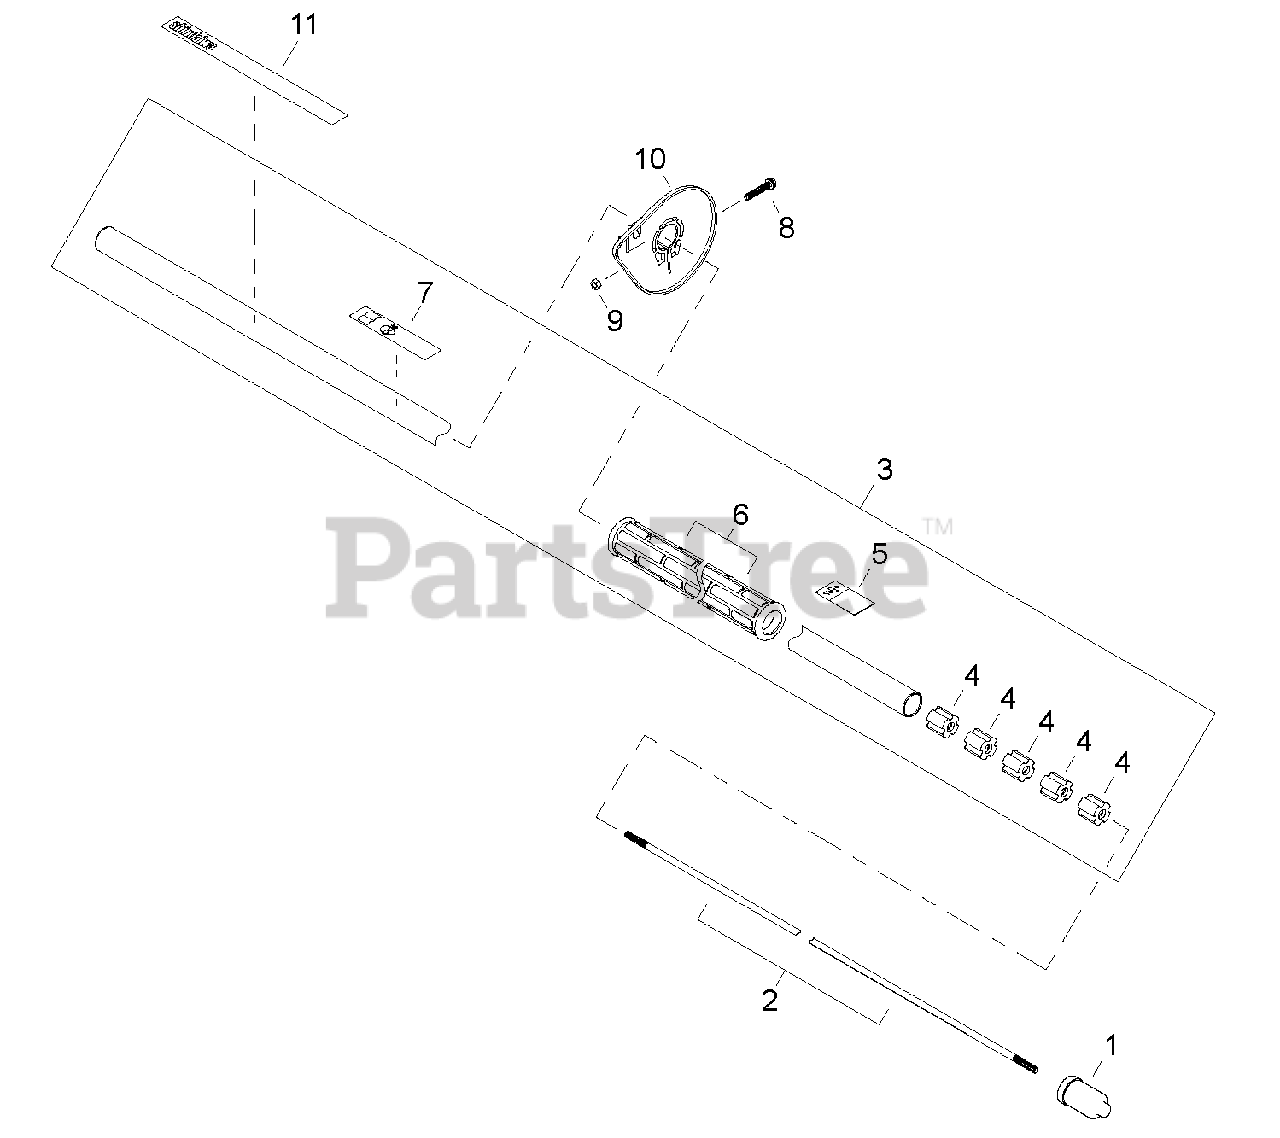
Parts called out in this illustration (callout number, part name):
1	CAP
2	PIPE, MAIN
3	MAIN PIPE ASSY
4	BUSHING
5	LABEL - HIGH VOLTAGE
6	GRIP - FRONT
7	LABEL - CAUTION
8	SCREW - 5X30
9	NUT - 5
10	PROTECTOR
11	LABEL - TRADE
